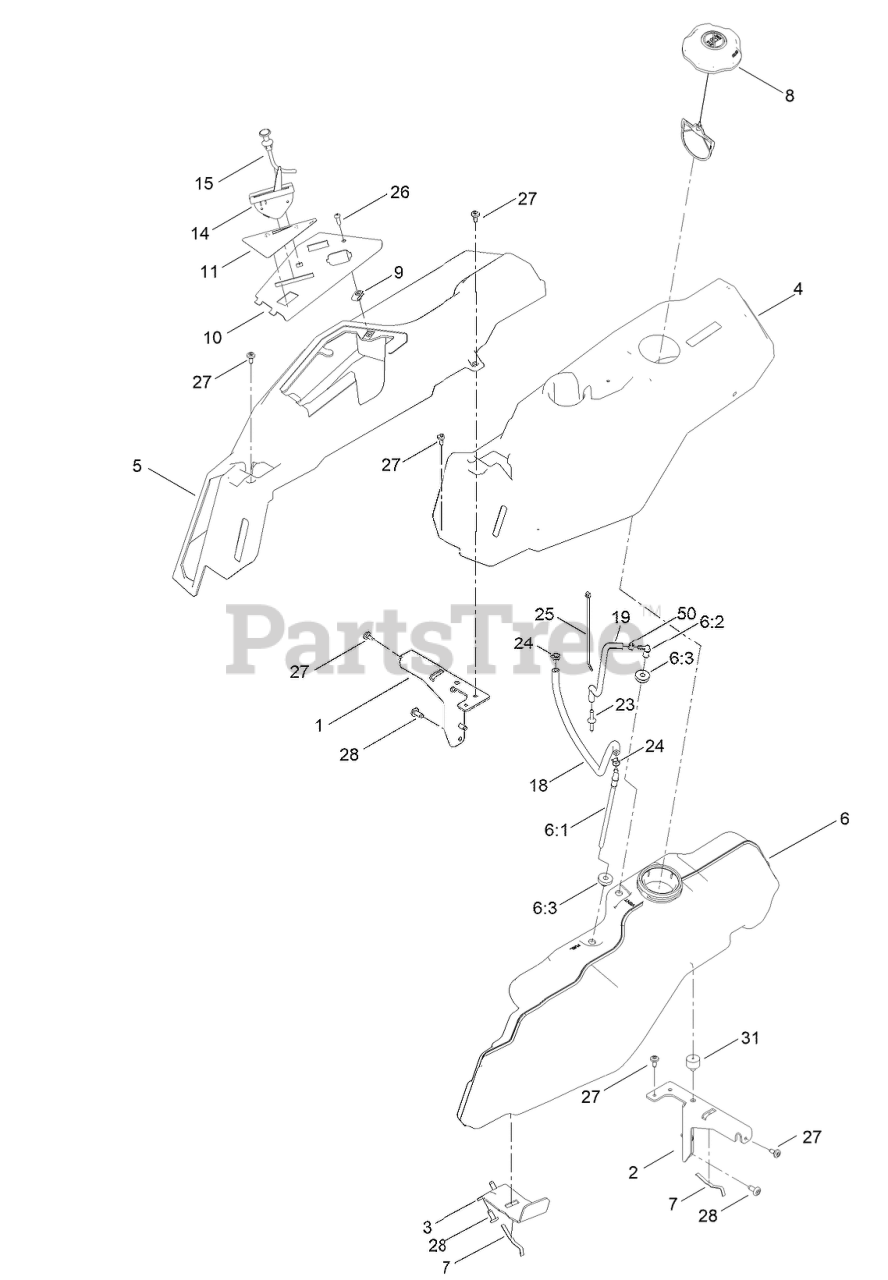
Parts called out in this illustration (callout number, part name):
1	SUPPORT-POD, RH
2	SUPPORT-POD, LH
3	SUPPORT-TANK, FUEL
4	POD-LH
5	POD-RH
6	TANK-FUEL ASM
6:1	CONNECTOR-ELBOW, 90 DEG
6:2	FITTING-ELBOW 90
6:3	BUSHING
7	SPRING
8	CAP-FUEL, RATCHETING
10	PANEL - CONTROL
11	DECAL-PANEL, CONTROL
14	CABLE-THROTTLE
15	CABLE-CHOKE
18	HOSE-FUEL
19	HOSE-FUEL
23	ADAPTER ORIFICE
24	CLAMP-HOSE
25	TIE-CABLE
26	SCREW-PRH
27	SCREW-SHOULDER
31	BUMPER-GROMMET
50	CLAMP-HOSE
